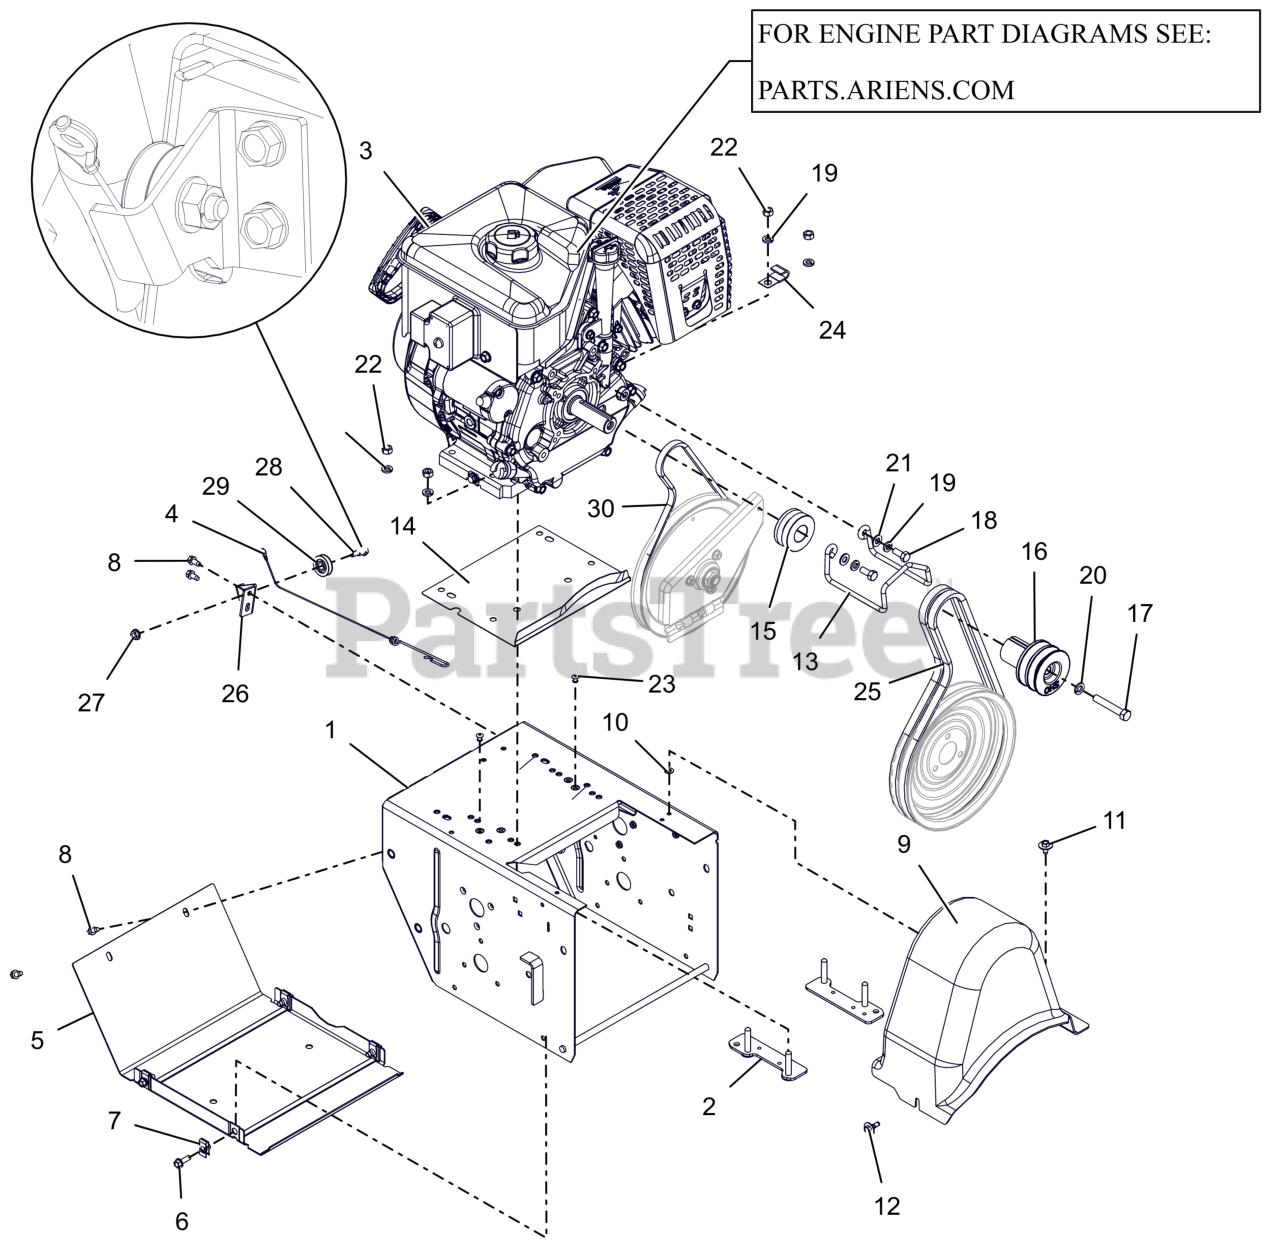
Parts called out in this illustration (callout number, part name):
1	FRAME, MAIN - 14GA DELUXE (ORANGE)
2	STRAP, ENGINE-MEDIUM BLOCK
3	ENGINE,EFI306 GEN3 120V/60W
4	CABLE, LOWER TRACTION,SS & PRO
5	COVER, BOTTOM
6	BLT, HWH .25-20X.75 G5 ZCC
7	NUT-RTNR .25-20X.56
8	SCR-TAP .25-20X.50 HWH ZCC
9	COVER, BELT-LARGE
10	NUT-PUSH .25X.50 O.D.
11	SCR, TAP .25-20X.50 LG HWH ZCC
12	SCR-TAP .25-20X.5 CAPTIVE
13	FINGER, BELT
14	BAFFLE, WATER - LARGE BLOCK
15	SHEAVE, TRACTION (KEYLESS)
16	SHEAVE,ATTACHMENT-SHO 2 GRV
17	BLT, HEX .38-24X2.25 G5 ZCC
18	BLT, HEX .31-24X.750 G5 ZCC
19	WSHR, LK-HVY .312X.097 ZCC
20	WSHR,LK-REG .375X.094 ZCC
21	WSHR,FLT .344X.688X.065 ZCC
22	NUT, HEX .312-18 ZCC
23	RVT, POP .1875 ZCC
24	J-CLAMP
25	V-BELT, HA-RAW EDGE (SET)
26	BRACKET, CABLE PULLEY
27	NUT-LK-TOP-FLG .250-20 GF ZCC
28	BOLT, SHLDR -.375 X .375 X .25-20
29	PULLEY, CABLE
30	V-BELT, 3L-WRAPPED
